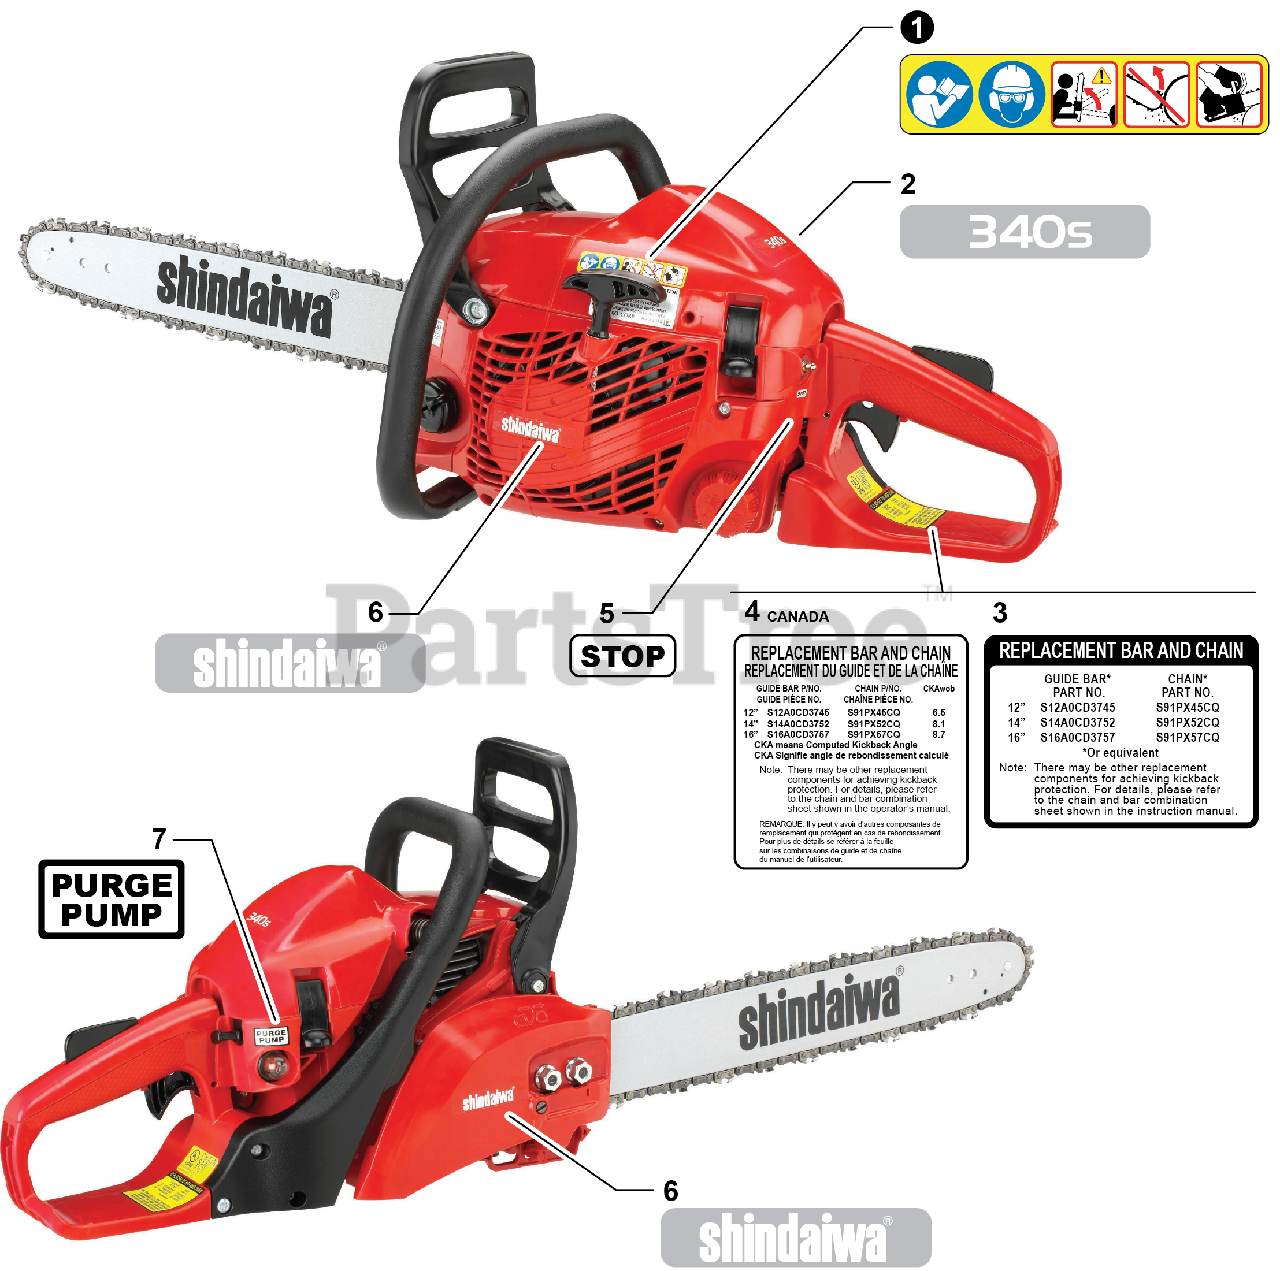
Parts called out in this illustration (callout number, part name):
1	LABEL, CAUTION
2	LABEL - MODEL 340s
3	LABEL, BAR & CHAIN
4	LABEL, BAR & CHAIN
5	LABEL, STOP
6	LABEL - shindaiwa
7	LABEL, PURGE PUMP
